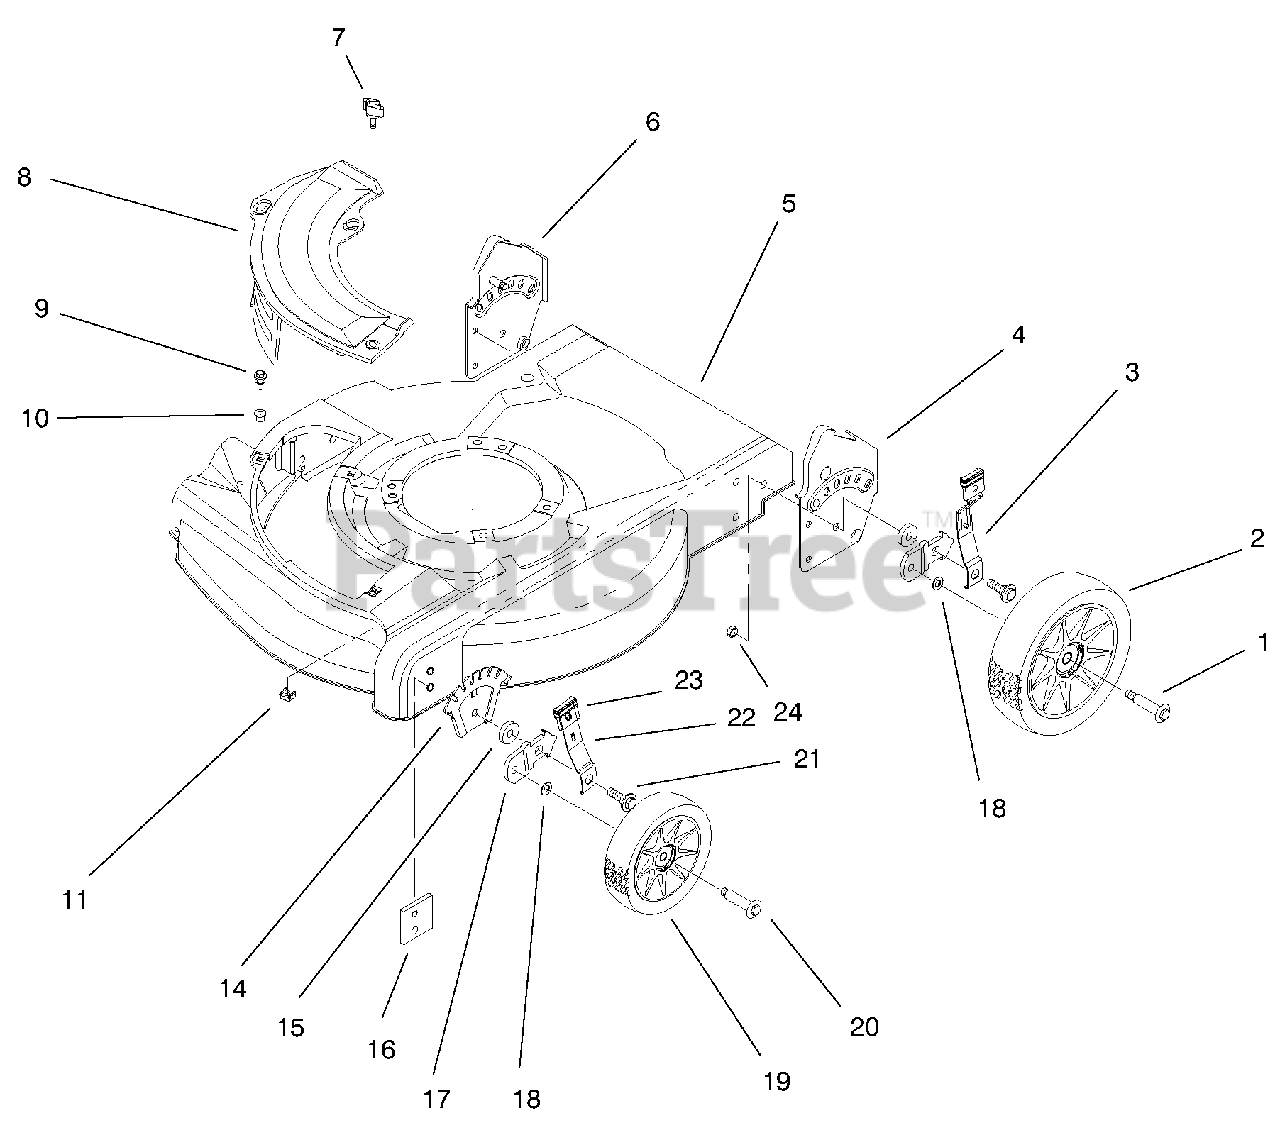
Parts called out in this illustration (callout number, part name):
1	Bolt-Shoulder
2	ASM-Wheel
3	ASM-Spring Arm
4	ASM-Handle Brkt
5	ASM-Housing & Baffle
6	RH Handle Bracket ASM
7	Knob-Cover Plate
8	Mulch Plate-21"
9	Screw-Sems
10	Grommet-Plastic
11	Nut-Cage
14	Plate-Height Adjust
16	Plate-Baffle
17	Bracket-Wheel Height Adj
19	ASM-Wheel & Tire 6"
20	Bolt-Shoulder
21	Bolt-Shoulder
22	Spring Arm-Front
23	Knob-Height Adjust
24	Nut-Lock
